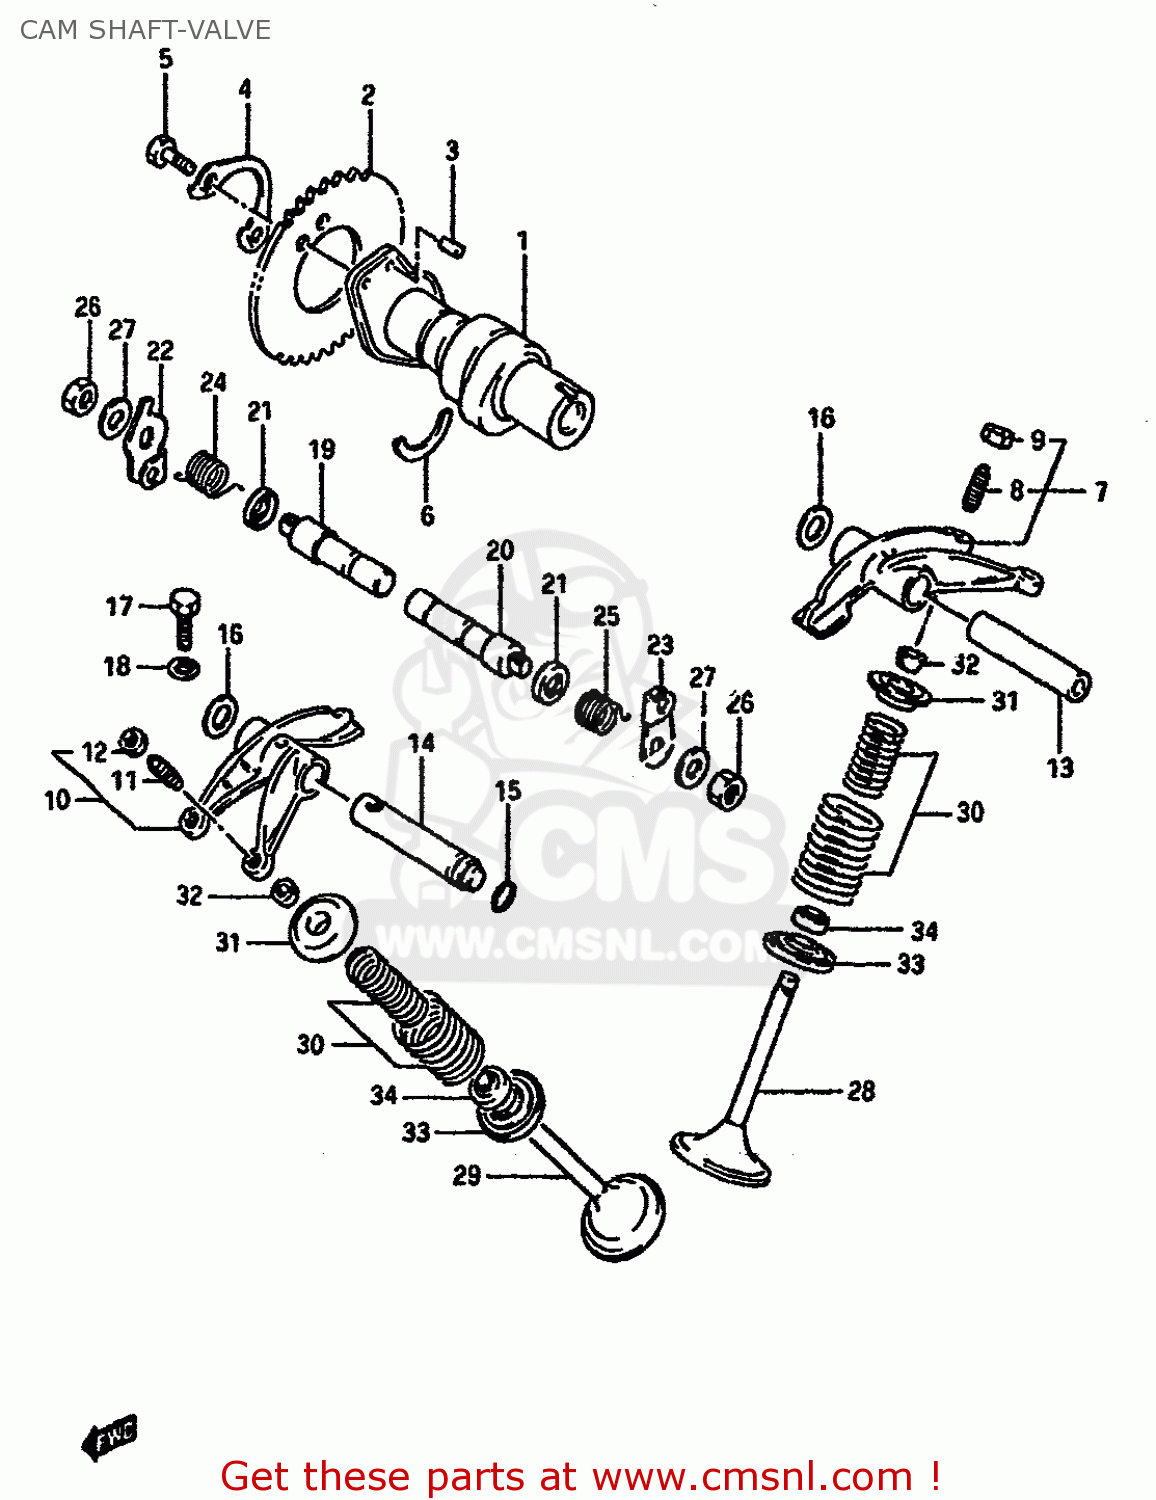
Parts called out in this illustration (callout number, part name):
1	CAMSHAFT
2	SPROCKET,CAMSHAFT(NT:42)
3	PIN
4	WASHER,CAM CHAIN SPROCKET
5	BOLT(6X12.5)
6	C RING
7	ARM,VALVE ROCKER,INTAKE
8	SCREW,TAPPET ADJUSTING
9	NUT,ADJUSTING SCREW
10	ARM,VALVE ROCKER EXHAUST
11	SCREW,TAPPET ADJUSTING
12	NUT,ADJUSTING SCREW
13	SHAFT,VALVE ROCKER ARM
14	SHAFT,EXHAUST VALVE ROCKER ARM
15	O RING(D:1.9,ID:8.6)
16	WASHER
17	BOLT 6X30
18	GASKET(5.8X13X1.2) (NAS)
19	SHAFT,DECOMP LH
20	SHAFT,DECOMP,L
21	OIL SEAL
22	LEVER,DECOMP SHAFT
23	LEVER,DECOMPRESSION SHAFT,LEFT
24	SPRING
25	SPRING
26	NUT 8MM
27	WASHER
28	VALVE,INTAKE
29	VALVE,EXHAUST
30	SPRING SET,VALVE
31	RETAINER,VALVE SPRING
32	COTTER VALVE
33	SEAT,VALVE SPRING
34	SEAL,OIL(7X14.4X9)
